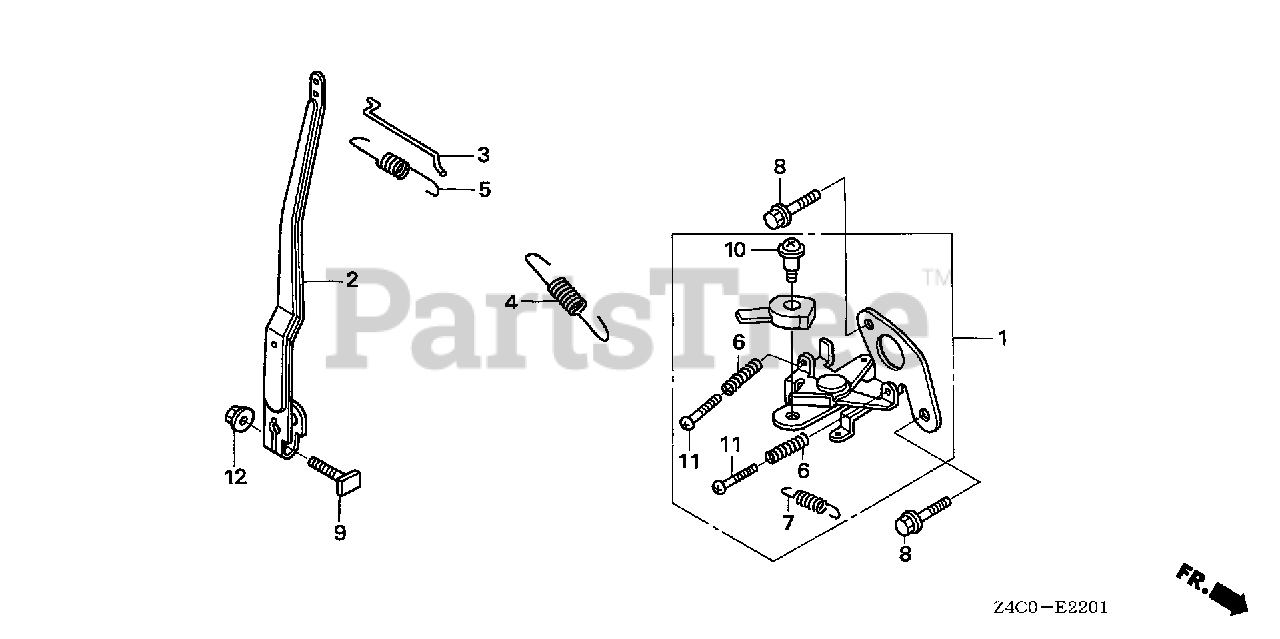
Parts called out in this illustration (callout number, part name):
1	CONTROL ASSY.
2	ARM, GOVERNOR
3	ROD, GOVERNOR
4	SPRING, GOVERNOR
5	SPRING, THROTTLE RETURN
6	SPRING, CONTROL ADJUSTING
7	SPRING, CABLE RETURN
8	BOLT, FLANGE (5X12)
9	BOLT, GOVERNOR ARM
10	SCREW, PAN (5X19)
11	SCREW, PAN (4X20)
12	NUT, FLANGE (6MM)
